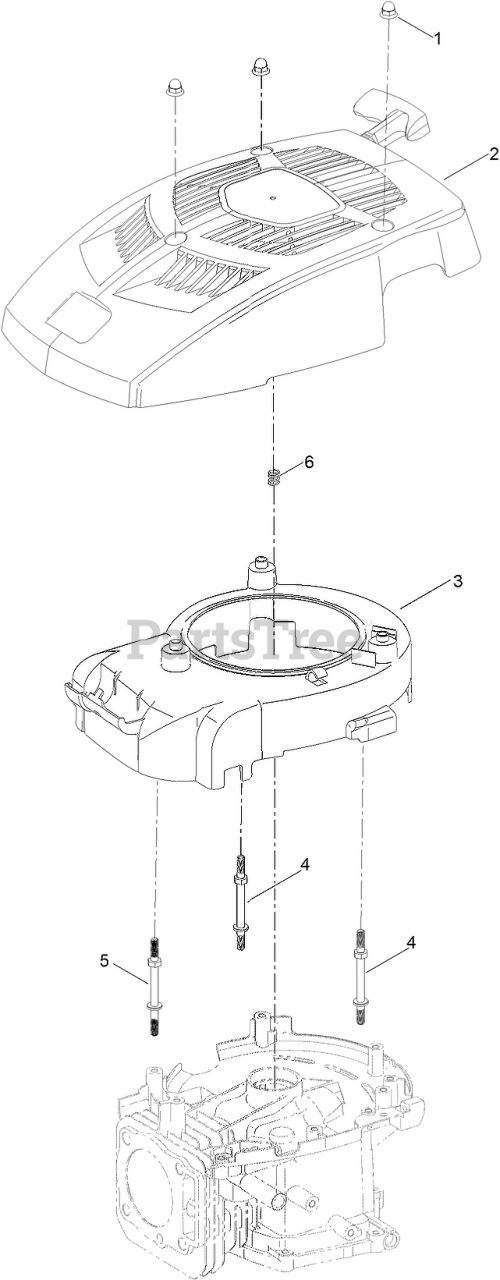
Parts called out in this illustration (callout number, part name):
1	NUT-ACORN
2	RECOIL SHROUD ASM
3	SHROUD-FAN
4	STUD-SHROUD
5	STUD-SHROUD
6	SPRING-COMPRESSION, RECOIL
